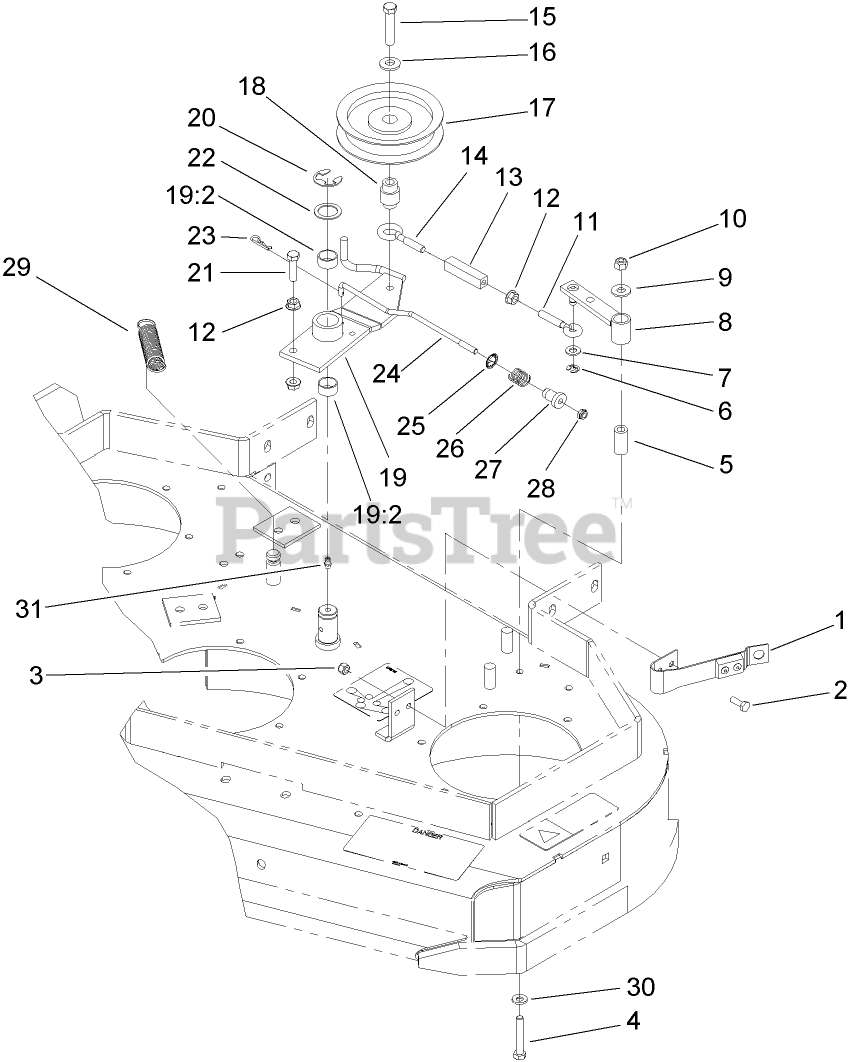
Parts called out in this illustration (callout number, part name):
1	PAD AND SPRING ASM
2	SCREW-HH
3	NUT-LOCK, NI
4	SCREW-HH
5	TUBE-PIVOT
6	RING-RETAINING, EXT
7	WASHER-PLAIN
8	ARM-ASSIST
9	WASHER-FLAT
10	NUT-LOCK, NI
11	EYEBOLT-THREAD, RH
12	NUT-HF
13	BODY-TURNBUCKLE
14	EYEBOLT-THREAD, LH
15	SCREW-HH
16	WASHER-BELLEVILLE
17	PULLEY-IDLER
18	BUSHING-ENGAGEMENT
19	Idler Arm ASM
19:2	SLEEVE-BEARING
20	RING-RETAINING, EXT
21	SCREW-HH
22	WASHER-SPINDLE
23	PIN-COTTER
24	ROD-BRAKE
25	RING-PUSH ON
26	SPRING-COMPRESSION
27	SPACER-FLANGED
28	NUT-LOCK, NI
29	SPRING-EXTENSION
30	WASHER-SPRING
31	FITTING-GREASE
